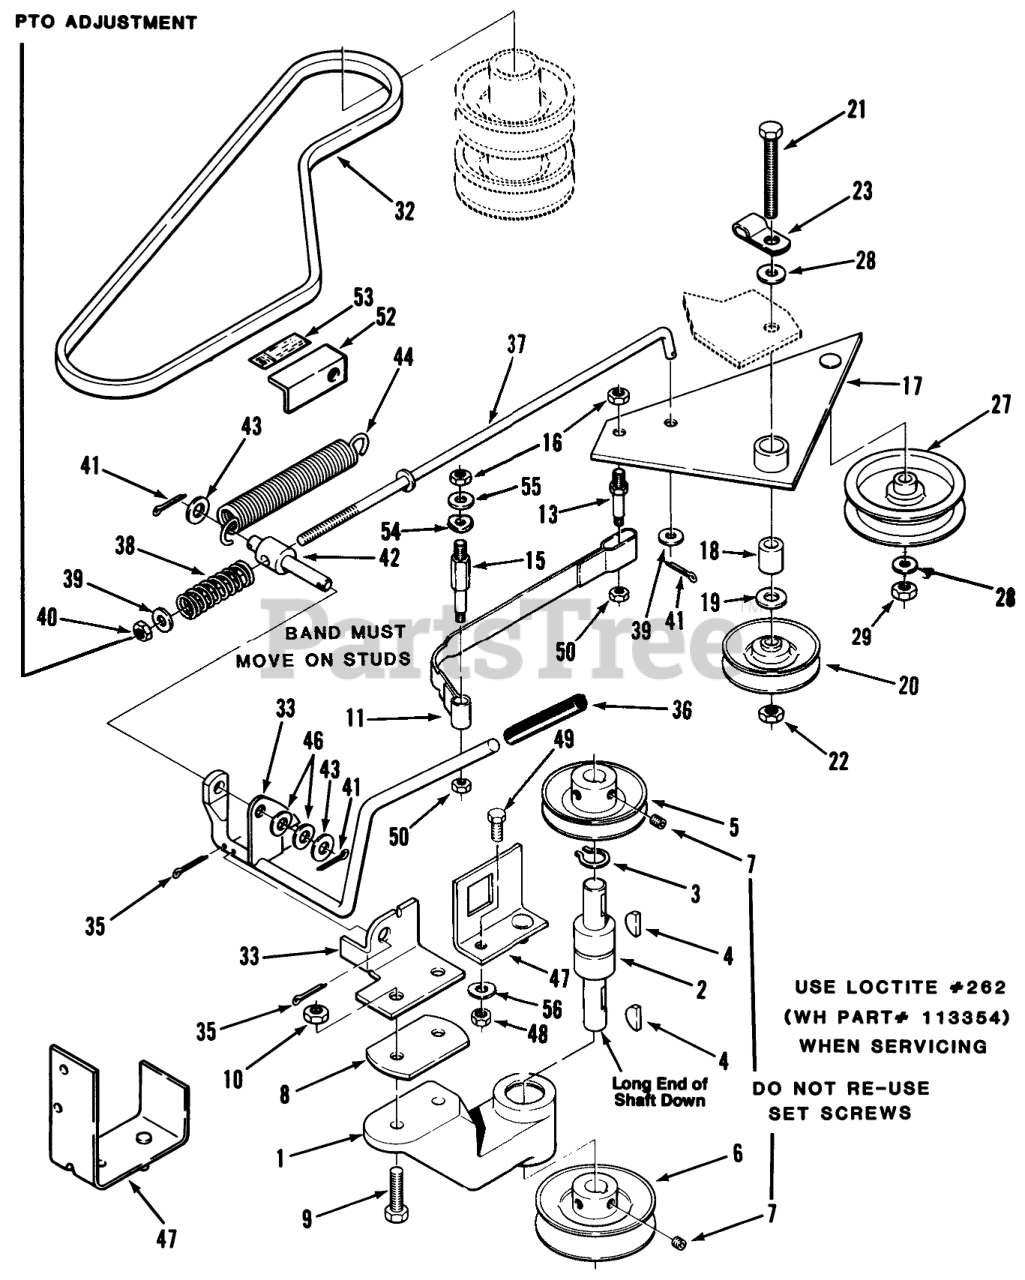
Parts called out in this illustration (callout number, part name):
1	Jack Shaft Housing
2	BEARING-INT SHAFT
3	Snap Ring
4	KEY-WOODRUFF
5	PULLEY CAST IRON
6	PULLEY
7	Set Screw
8	PLATE SPACER R
9	Bolt
10	NUT
11	BAND BRAKE
13	STUD-SHOULDER
15	STUD-SHOULDER LONG
16	Nut
17	BLADE LEVER ASSY R
18	SPACER
19	Washer
20	IDLER PULLEY
21	Bolt
22	NUT
23	CLAMP DOUBLE
27	Idler Pulley
28	Washer
29	NUT-HEX, JAM
33	ASSY HANDLE PTO CLUT
35	Cotter Pin
36	GRIP
37	ASSY ROD PTO
38	SPRING COMPRESSION
39	WASHER 5/16 SAE
40	Nut
41	Cotter Pin
42	TRUNNION
43	Washer
44	SPRING R
46	WASHER-SPRING
47	ASSY BRACKET SWIT R
48	Nut
49	H H C S
50	Nut
52	PTO INDICATOR BRC R
53	DECAL-PTO BELT ADJ
54	WASHER
55	WASHER 5/16 SAE
